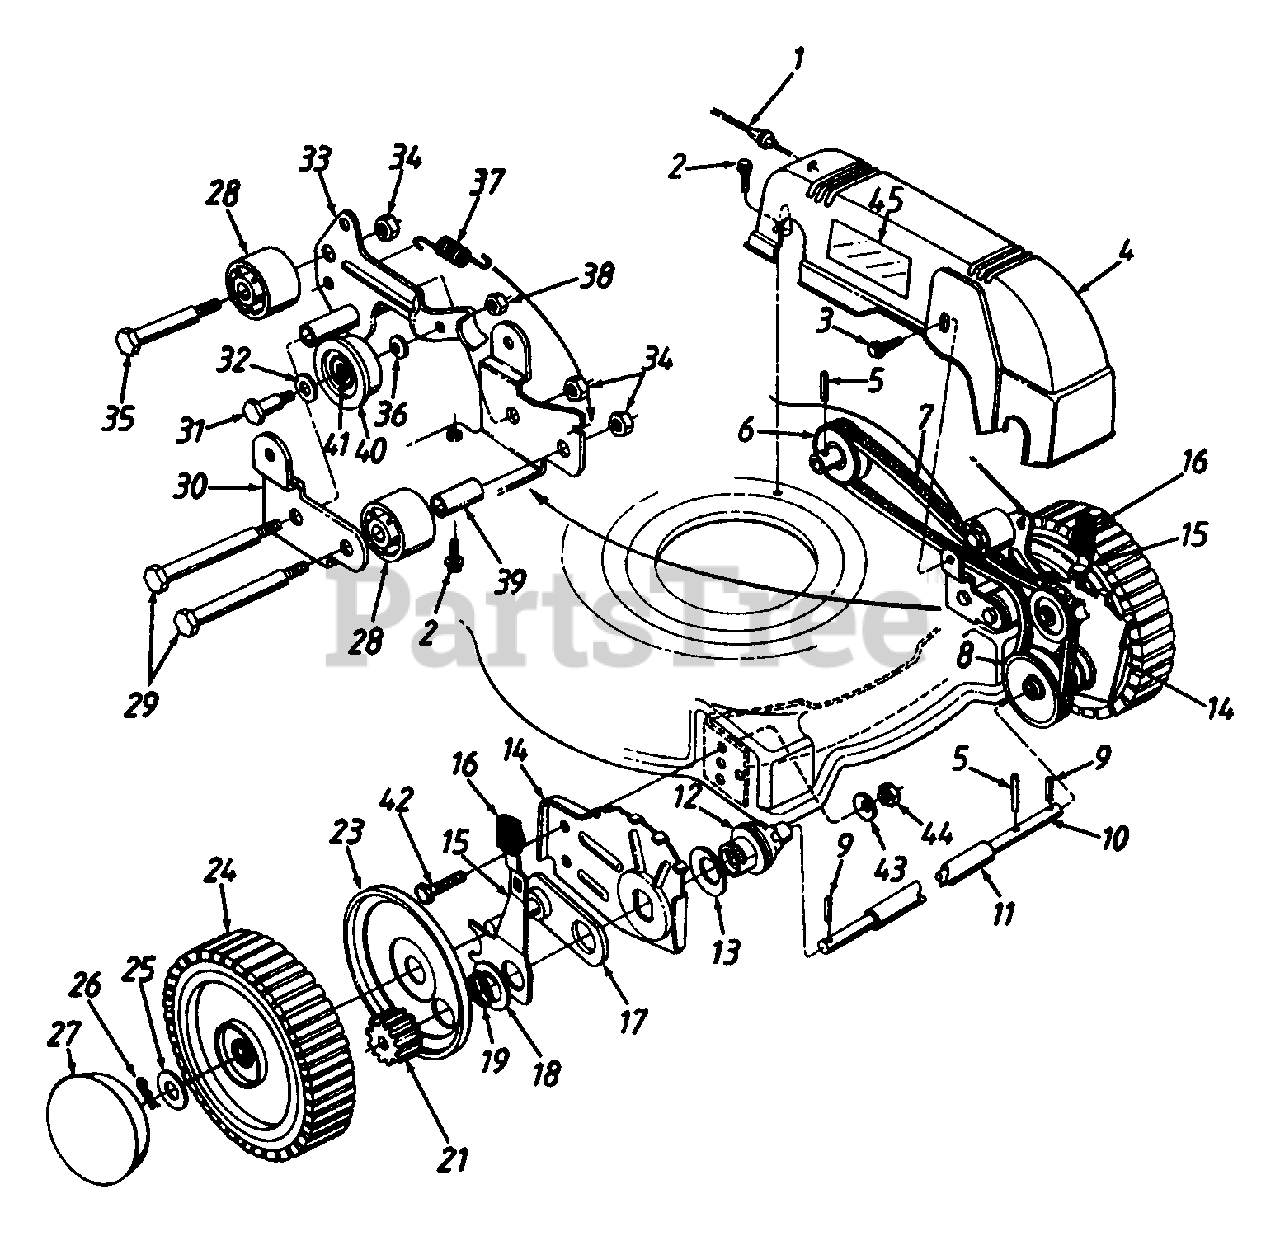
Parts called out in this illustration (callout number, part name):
1	S.P. Cable 44.75" Lg.
2	Hex Wash. Hd. TT-Tap Scr. 1/4 - 20 x .5" Lg.
3	Hex Wash. Hd. Tap Scr. 1/4 - 20 x .38" Lg.
4	Belt Cover
5	Spring Pin 3/16" Dia. x 1.25" Lg.
6	3/8" "V" - Pulley 2.75" O.D.
7	"V" - Belt
8	3/8" "V" - Pulley 2.44" O.D.
9	Spring Pin 3/16" Dia. x .875" Lg.
10	Front Axle
11	Axle Shroud
12	Front Bearing Ass'y.
13	Wave - Wash. 1.01" I.D.
14	Height Adj. Plate - R.H.
15	Spring Lever - R.H.
16	Spring Lever Knob
17	Height Adj. Pivot Plate Ass'y.
18	DD Washer 1.5" O.D.
19	Snap Ring
21	14-T Spur Gear
23	Wheel Dust Cap
24	Front Wheel Ass'y.
25	Fl-Wash. .531" I.D. x 1" O.D.
26	Hairpin Clip
27	Hub Cap - 3-1/2" Dia. (Gray)
28	Idler Ass'y.
29	Shld. Bolt .374" Dia. x 1.94"
32	Fl-Wash. .39" I.D. x 1" O.D.
35	Shld. Bolt 3/8" Dia. x 1.16"
36	Bell-Wash. .265" I.D. x .75" O.D.
37	Spring Extension 1.29" Lg.
38	Hex Nut 1/4 - 28 Thd.
39	Spacer .385" I.D. x .625" 0 D.
40	Fl-Idler 1.5" O.D.
41	Needle Brg. .375" I.D.
42	Hex Bolt 3/8 - 16 x .62" Lg.
43	Bell-Wash. .39" I.D. x 1.13" O.D.
44	Hex Nut 3/8 - 16 Thd.
45	Foil Label
